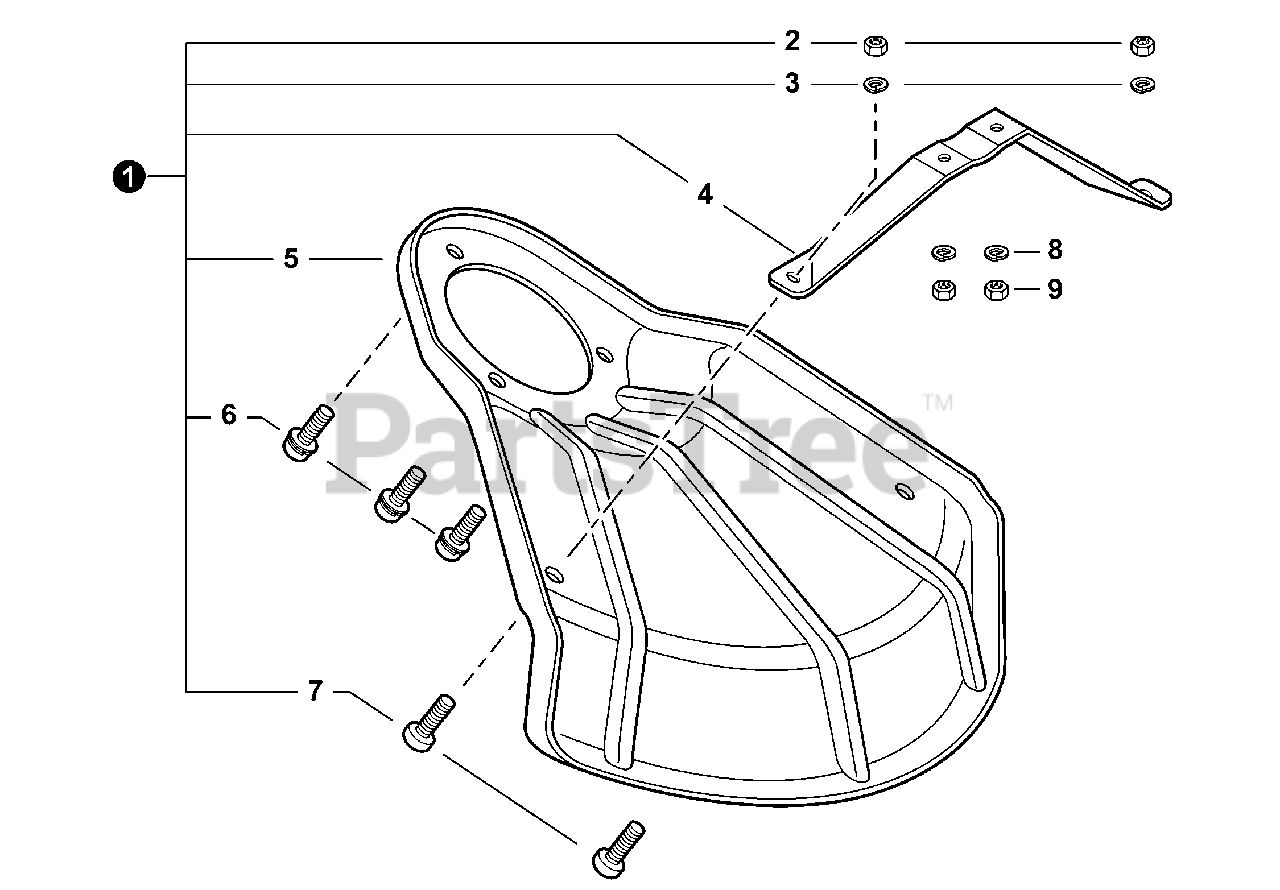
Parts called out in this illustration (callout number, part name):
1	SHIELD ASSY, METAL DEBRIS
2	NUT M5
3	WASHER, SPRING 5
4	BRACKET, SHIELD MOUNTING
5	SHIELD, METAL DEBRIS
6	SCREW 5×10
7	SCREW 5×8
8	WASHER, SPRING 5
9	NUT M5
